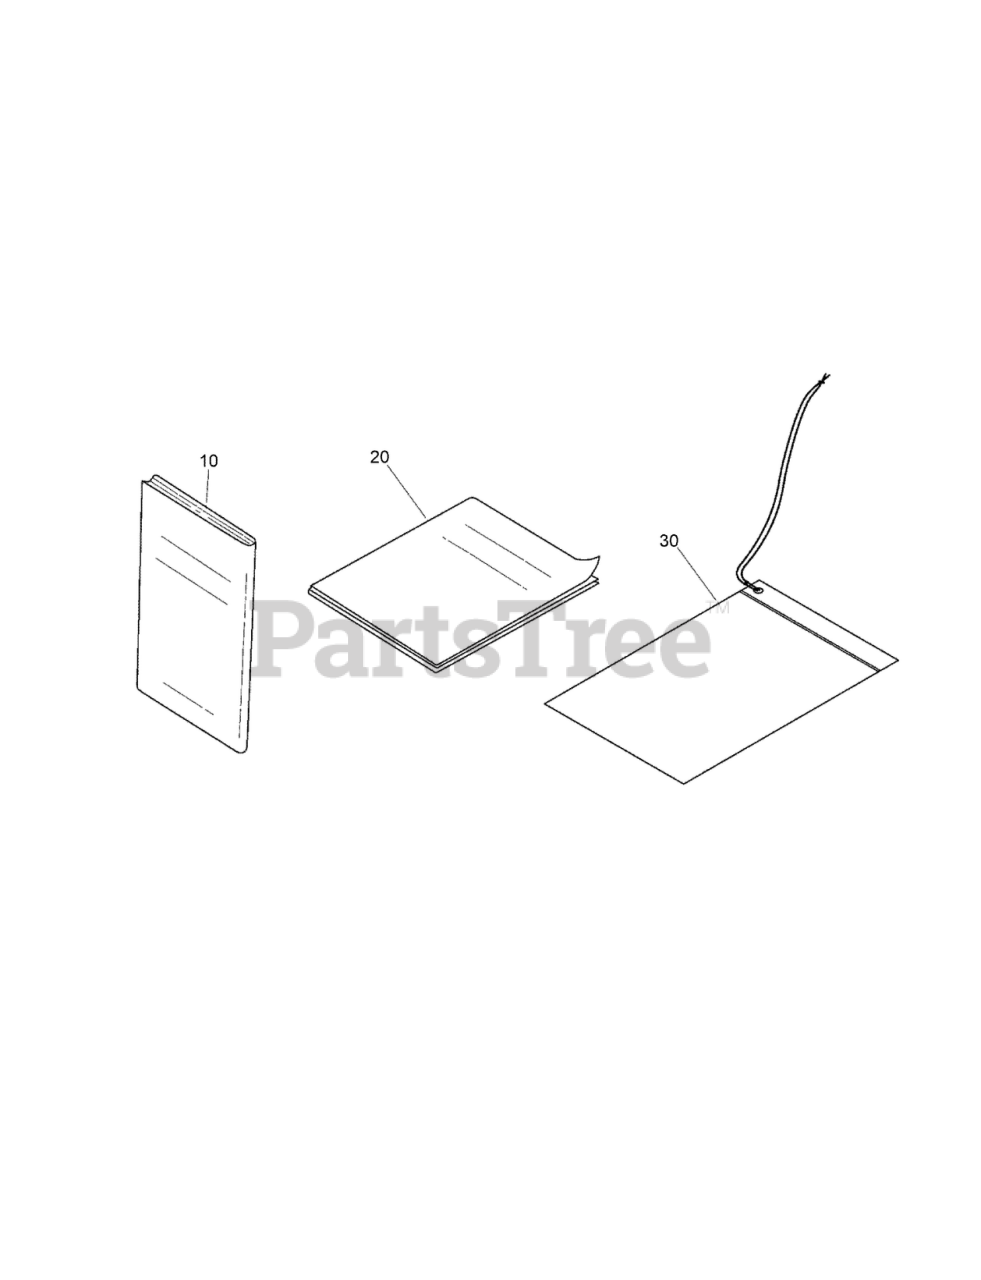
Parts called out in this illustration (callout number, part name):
10	MANUAL,OP
20	MANUAL,INST
30	BAG-PLASTIC
